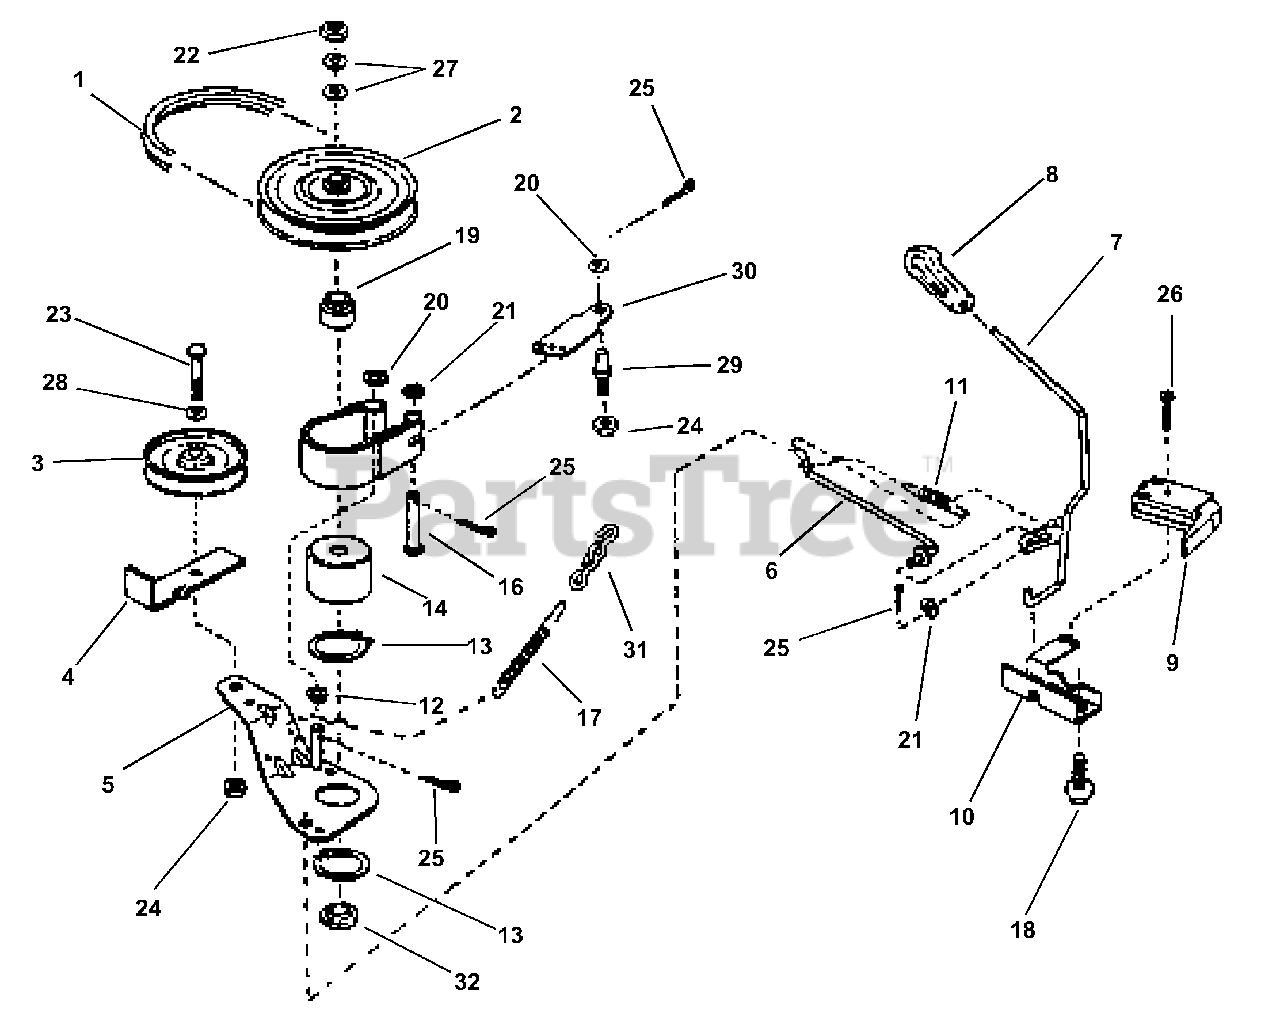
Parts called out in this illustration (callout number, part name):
1	BELT, Drive (72.25" AA Section)
2	PULLEY, Spindle
3	PULLEY, Idler
4	RESTRICTOR, Belt
5	ARM, Idler
6	ROD, Idler
7	HANDLE, Blade Lever (On-Off)
8	GRIP, Handle
9	SWITCH, Deck Interlock
10	MOUNT, Handle
11	SPRING, Blade Handle
12	SPACER
13	RING, 2" External Retaining
14	DRUM, Brake
16	PIN, 1/4 x 1-5/8" Clevis
17	SPRING
18	SCREW, 1/4-20 x 5/8" Hex Washer Self-Tap
19	HUB, Pulley
20	WASHER, 3/8" Flat
21	WASHER, 1/4 Flat
22	NUT, 3/4-16 Hex Jam
23	SCREW, 3/8-24 x 1-3/4" Hex Cap
24	NUT, 3/8-24 Hex Nyloc
25	PIN, 3/32 x 3/4" Cotter
26	SCREW, #10-32 x 1" Self-Tap
27	WASHER, 49/64 x 1-1/2" Flat
28	WASHER, 3/8" Flat
29	STUD (3/8-24 Thread)
30	BRACKET, Brake Anchor
31	LINK, Chain
32	WASHER, Spindle
